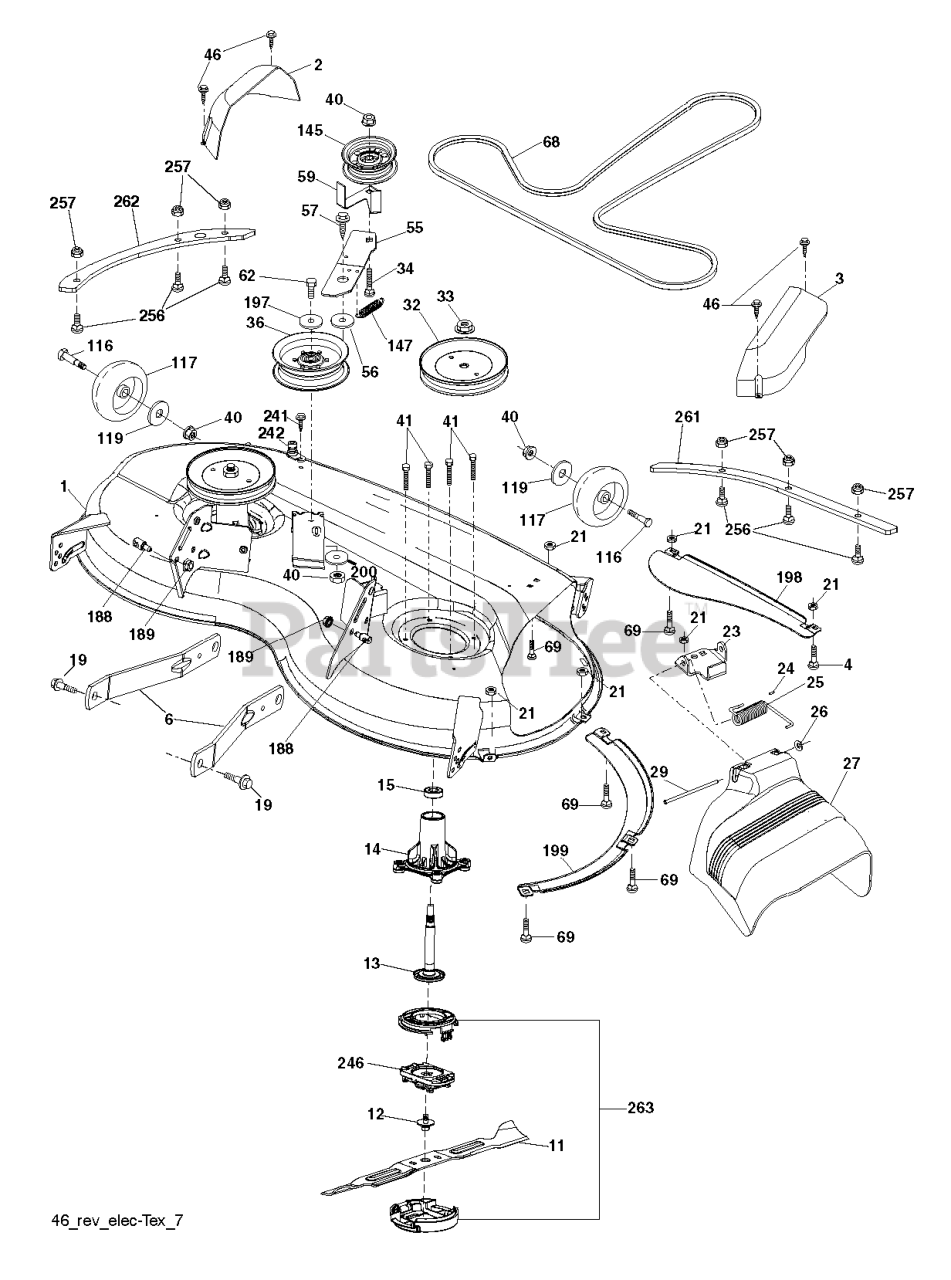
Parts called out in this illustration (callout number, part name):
1	KIT.SVC.WELDMNT.46"405050X498
2	COVER.MANDREL.LH.46"
3	COVER.MANDREL.RH.46"
4	BOLT
6	ARM.SUSPENSION.MOWER.R
11	BLADE.REVOLTION.46"BAGER.PT43
12	SCREW.SEMS.7/16-20X1.HEX.HEAD
13	RP.SAFT ASM.REV.TALL.N/GREASE
14	RP.HOUSG.MAND.REV.TALL.N/GRS
15	BEARING.MANDREL.TOP.EXTENDED
19	BOLT.SHOULDER
21	LOCKNUT
23	BRKT.DEFLECTOR.38"2005+
24	CAP-SLEEVE LT
25	SPRING.TORSION.DEFLECT
26	NUT PUSH M
27	SHIELD.DEFLECTOR.MOWER.46"BLAC
29	ROD.HINGE
32	PULLEY.MANDREL.5.438.PD
33	NUT.FLANGE.LOCK.TOP
34	BOLT.3/8-16X1.50
36	PULLEY.IDLER.2006
40	NUT LOCK FLG 3/8-16 UNC
41	BOLT.HEX.WASHR.HED.313-18X1.19
46	SCREW.1/4-20X5/8
56	SPACER.RETAINER
57	SCREW 3/8-16X1
59	GUARD, BELT
62	BOLT-HEX EAK
68	V-BELT
69	BOLT
116	BOLT M
117	WHEEL.GAGE.HALF.SPOKED
119	WASHER.5/16.FLAT.STE.STD.
145	PULLEY.IDLER.48"PRIMARY
147	SPRING.MOWER.DRIVE.ELECTRIC
188	STUD.FASTNER.W/ANTI-ROTATE
189	NUT LOCK HEX FLANGE 5/16-18
197	WASHER
198	BAFFLE CENTER FRONT
199	BAFFLE FRONT RH
200	WASHER.13/32 X 1 X 1/2.11GUARD
241	SCREW.TT.#10-32X.5.3/8.FLANGE
242	PORT.WASHOUT
246	HOLDER.BLADE.REVOLUTION
256	RHSNB, 1/4-20 X 1, GR5
257	NUT T
261	PLATE.REINF.DECK.46".FRONT.BLK
262	PLATE.REINF.DECK.46".SIDE.BLK
263	CAP.REVOLUTION ASM
